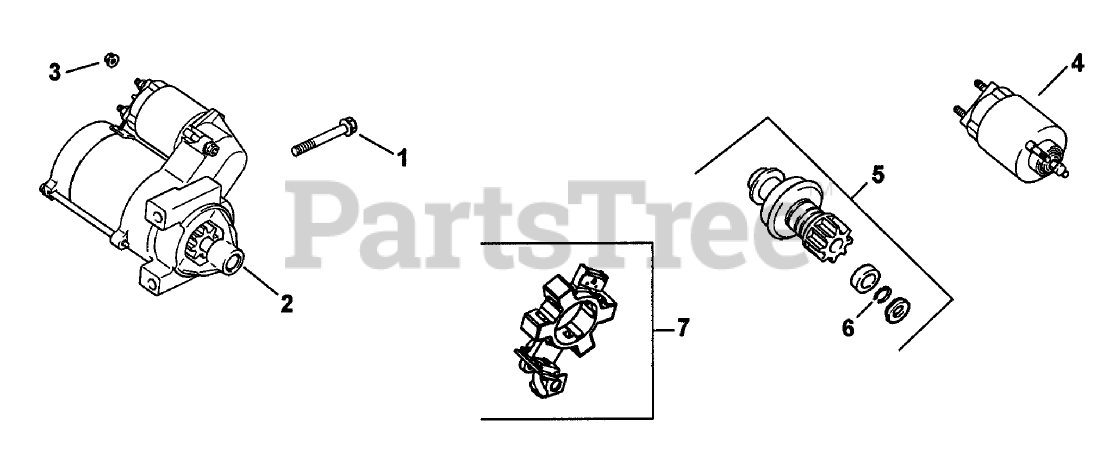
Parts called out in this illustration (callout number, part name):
1	SCREW-FLG (M8X1.25X80)
2	Solenoid Shift Starter ASM (Includes 4-7)
3	NUT-FLANGE (M8X1.25)
4	Solenoid Kit
5	Kit-Drive, Pinion (Includes 6)
6	RING-RETAINING
7	BRUSH HOLDER KIT
